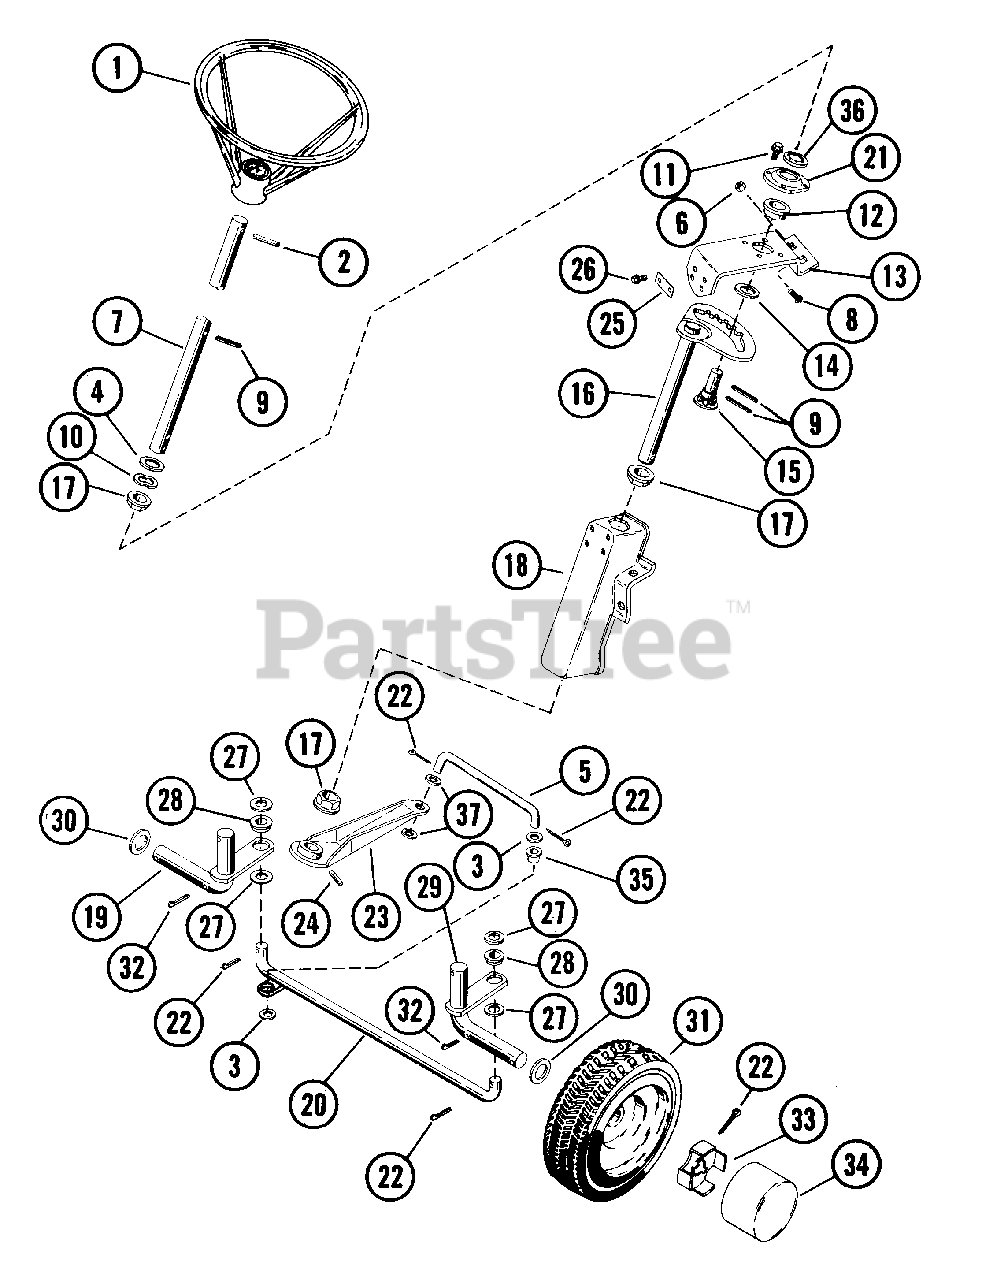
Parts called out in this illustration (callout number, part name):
1	STEERING WHEEL
2	PIN-ROLL .250X1.75
3	WSHR-FL-STL .382X.812X.023 PL
4	WSHR-FL-STL .755X1.375X.062 PL
5	STEERING LINK
6	NUT-LK .312-18 GR A PL
7	STEERING SHAFT
8	BLT-RDHDSQSHNK .31-18X.50 YZ
9	PIN-ROLL .188X1.00
10	SPRING WASHER
11	SCR-TAP 10-24X.25 CRSLPH PL 1A
12	BSHG-FLG .625X1.156X.375 SI
13	STEERING SUPPORT
14	WSHR-FL-STL .630X1.005X.062 PL
15	STEERING PINION
16	STEERING GEAR
17	FLANGE BUSHING
18	DEEP DRAW STEERING BOXES
19	R H WHEEL SPINDLE
20	TIE ROD
21	RETAINING PLATE
22	PIN-COTR .12X1.0 PL
23	STEERING ARM
24	PIN-GRV .188X1.25 TP A
26	BLT-SERHFWH .31-18X.75 PL
27	WSHR-FL-STL .505X.875X.024 PL
28	BSHG-FLG.500X.625X.312X.750NY
29	L H WHEEL SPINDLE
30	SPINDLE WASHER
31	FRONT WHEEL ASSEMBLY
31	TIRE 4.10/3.50-4
31	WHL
31	ZERK FITTING
31	BSHG-FLG .750X1.380X.750X1.557
32	PIN-COTR .12 X 1.25 PL
33	SPINDLE CUP
34	HUB CAP
35	BSHG-FLG .372X.500X.312X.625NY
36	PUSH NUT, .50
37	WSHR-FL-STL .406X.865X.094 PL
